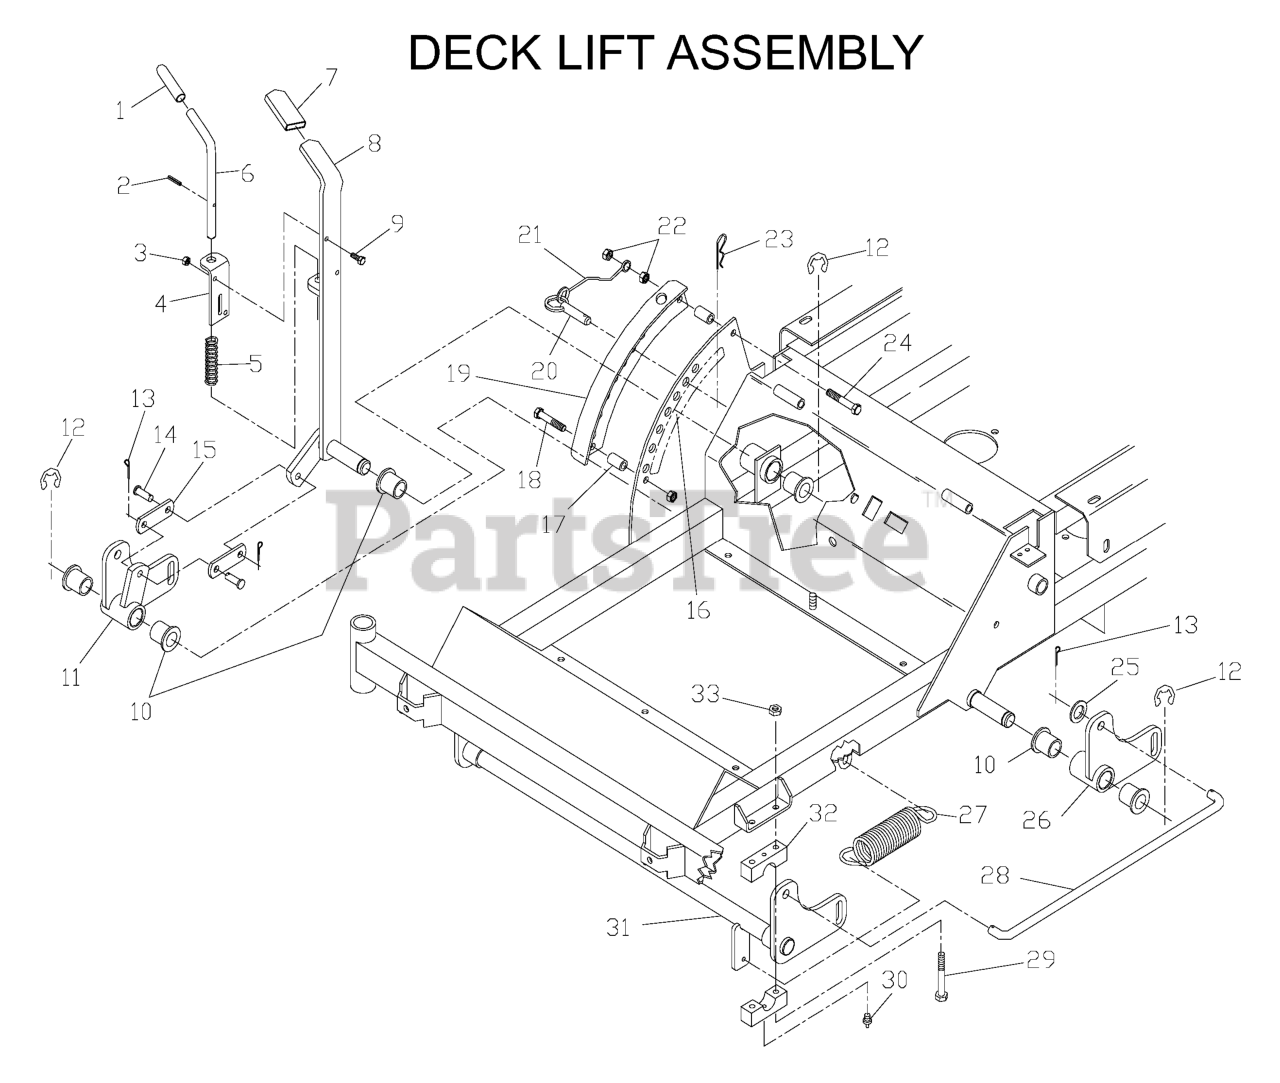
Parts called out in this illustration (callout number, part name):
2	ROLL PIN 3/16 X 1-1/4 ZD
3	NUT 1/4C CENTER LOCK
4	PIN MT, UPPER
8	LEVER WELDMENT
9	HCS 1/4C X 3/4 HCS
10	BUSHING, FLANGED
11	BELLCRANK WLDMT - RT
12	E-RING 7/8
13	RP_COTTER PIN 1/8 X 3/4
14	CLEVIS PIN 3/8 X 1 1/8
16	DECAL, LOCATOR
18	HCS 3/8C X 2
19	LOCATOR WELDMENT
22	NUT 3/8C CENTERBLOCK
23	HAIRPIN #4
24	HCS 3/8C X 2 1/4
25	BUSHING 1/2 MACH
26	BELLCRANK WLDMT-LT
29	BOLT 5/16C X 2 1/2
31	LIFT WLDMT
32	LIFT BLOCK
33	NUT 5/16C CENTERLOCK
